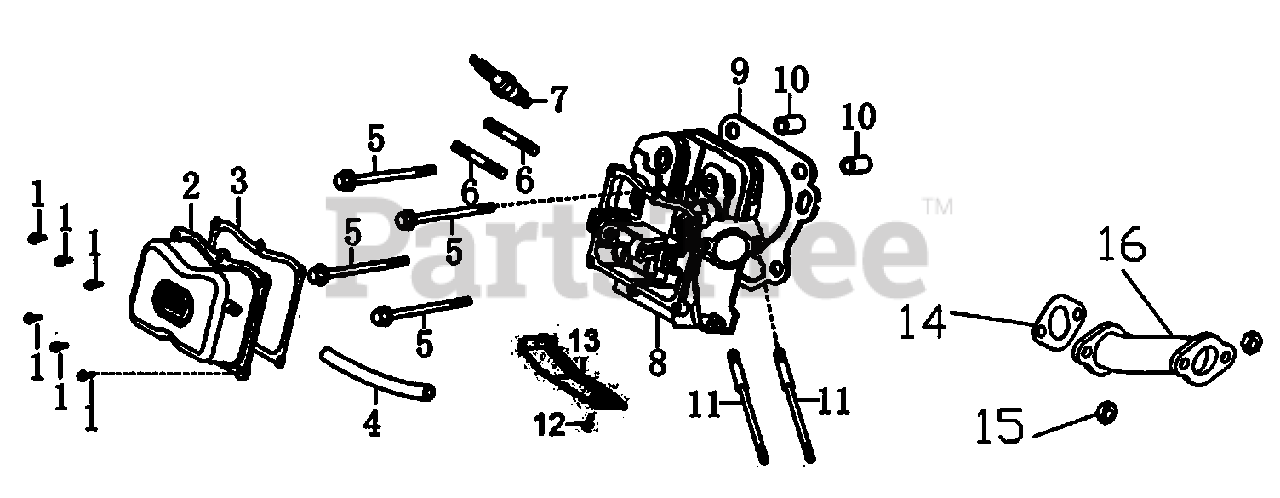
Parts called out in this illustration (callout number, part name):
1	BOLT, FLANGE
2	COVER, HEAD
3	GASKET, HEAD COVER
4	TUBE, BREATHER
5	BOLT, FLANGE 10X80
6	BOLT, STUD EXHAUST
7	SPARK PLUG
8	CYLINDER HEAD
9	GASKET, CYLINDER
11	BOLT, STUD INTAKE
12	BOLT, FLANGE M6X12
14	GASKET, EXHAUST CYLINDER
16	MANIFOLD, EXHAUST
